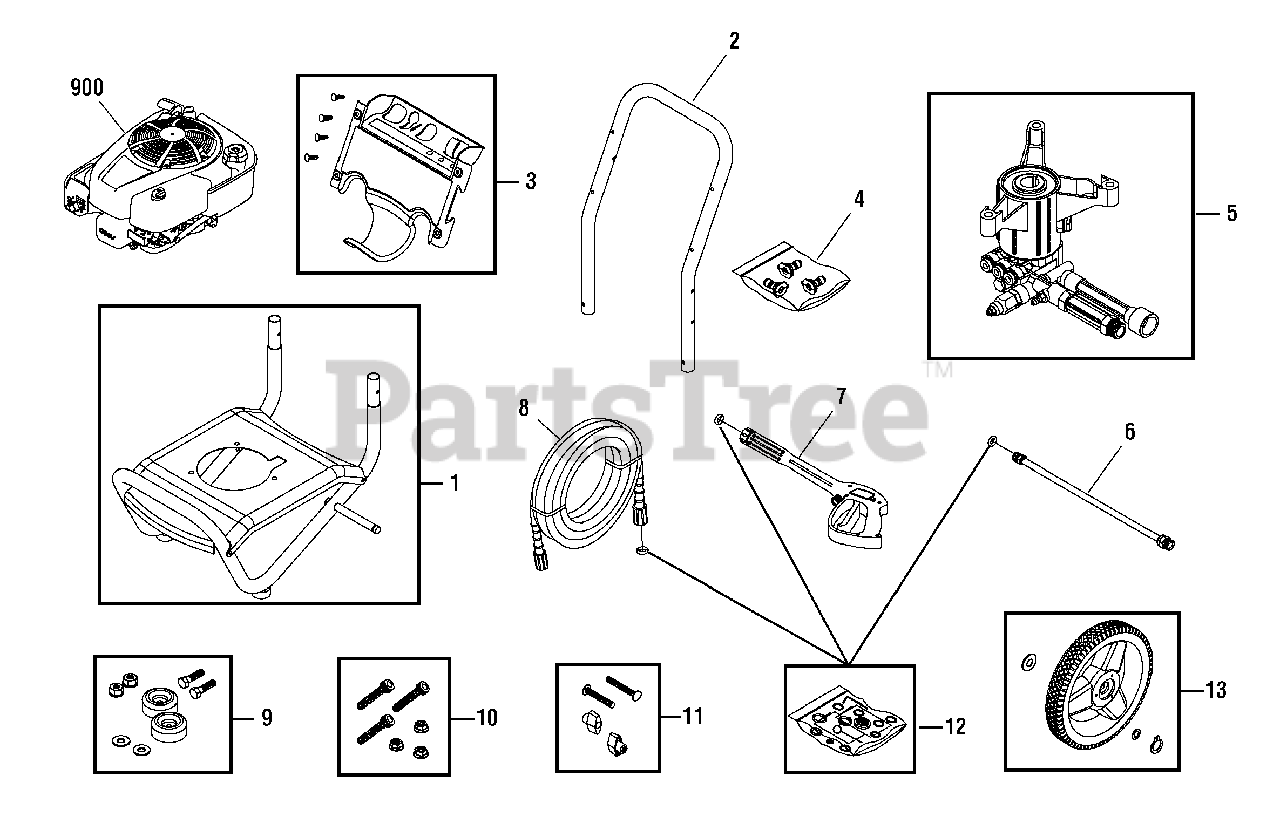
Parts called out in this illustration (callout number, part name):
4	KIT, QC Nozzles
6	EXTENSION, QC
7	GUN
8	HOSE
9	MOUNT, Vibration
10	KIT, Hardware, Pump Mounting
11	KIT, Hardware, Handle
12	KIT, O-Ring
900	* ENGINE
